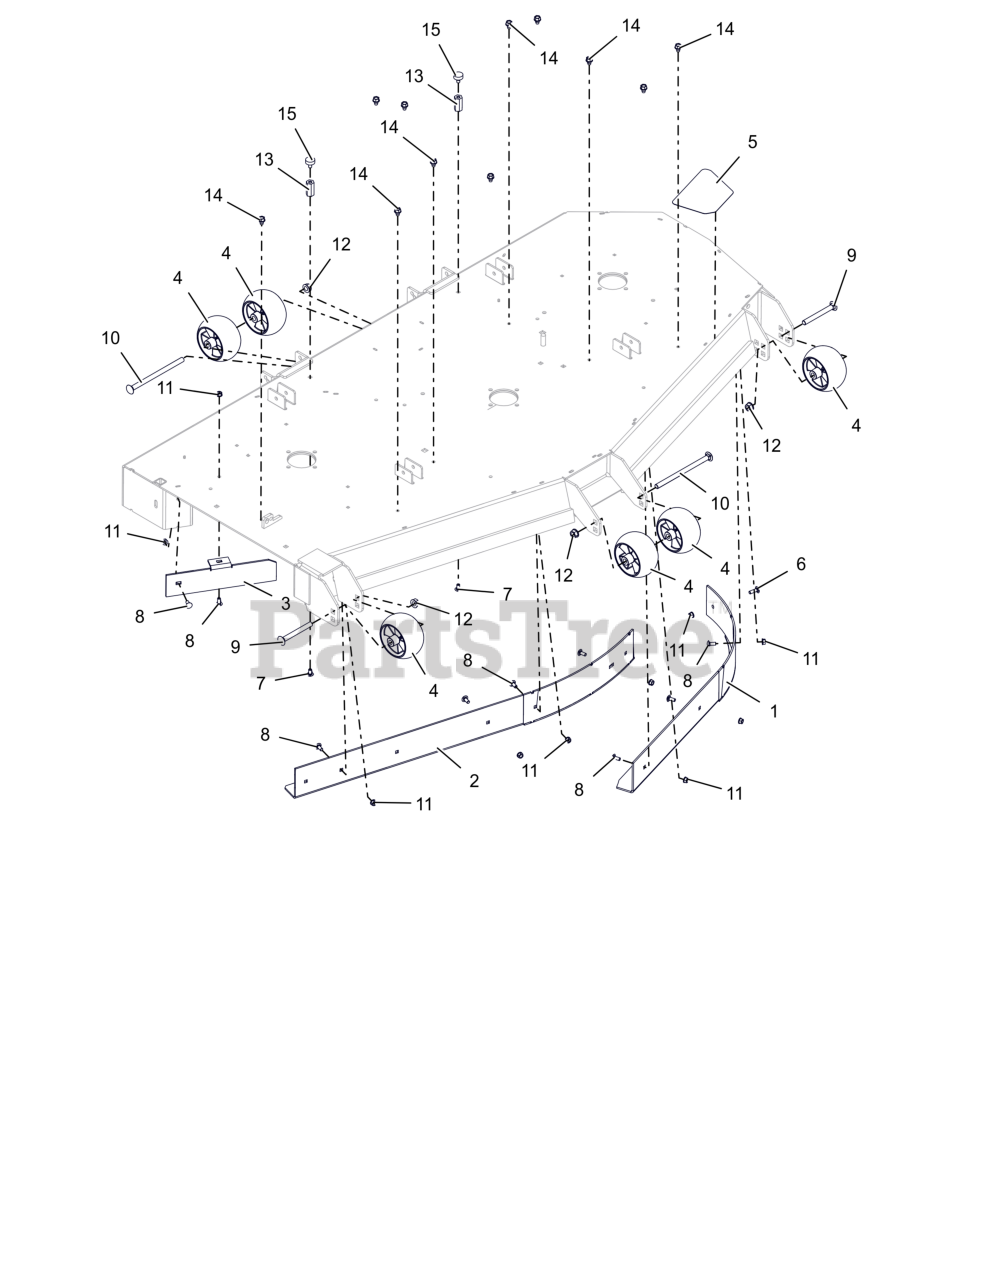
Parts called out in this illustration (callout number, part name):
1	WLDMT, 72" LH VACUUM BAFFLE (RED)
2	WLDMT, VACUUM BAFFLE 72" RH (RED)
3	72" DISCHARGE BAFFLE - RED
4	WHEEL, ANTI SCALP - 5X3 CTR W/RIBS
5	GRIP, STEP ANTI SKID
6	BLT,RHSSN .31-18X1.00 G5 ZCC
7	BTL,RHSSN .313-18 X 0.625 G5 ZCC
8	BLT, RHSSN.31-18X.750 G5 ZCC
9	BLT,RHNS .50-13X4.50 G5 ZCC NS
10	BLT,RHSN .50-13X8.00 G5 ZCC NS
11	NUT,LK-CTR-FLG .31-18 GF ZCC
12	NUT-LK-CTR-FLG .500-13 GG ZCC
13	NUT, COUPLING .312-18 X 1.625
14	SCR,TAP .375-16X.50 HWH TR ZCC
15	BUMPER, RUBBER
